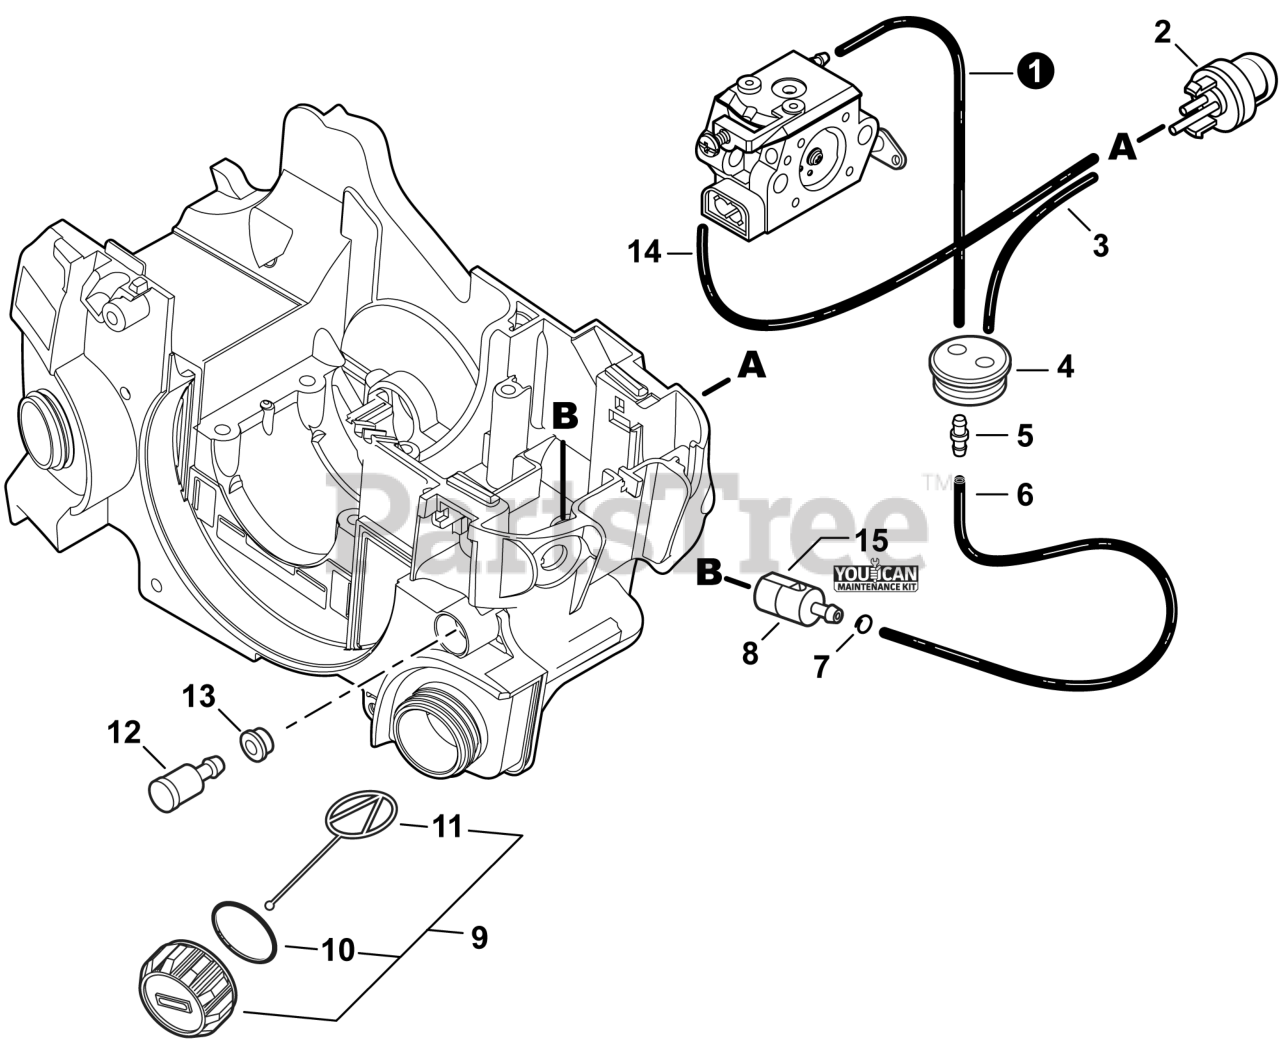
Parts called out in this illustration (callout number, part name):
1	PIPE, FUEL 3x5x85 BLACK
2	BULB, PURGE
3	PIPE, FUEL 2.4x5x80 BLACK
4	GROMMET, FUEL
5	CONNECTOR, PIPE
6	PIPE, FUEL 3x5x144 BLACK
8	FILTER, FUEL
9	CAP ASSY, FUEL
10	O-RING 22
11	CONNECTOR, CAP L= 60 MM
12	VENT ASSY
13	GROMMET, FUEL
14	PIPE 2.4x5x125 BLACK
15	TUNE-UP KIT - YOUCANT
